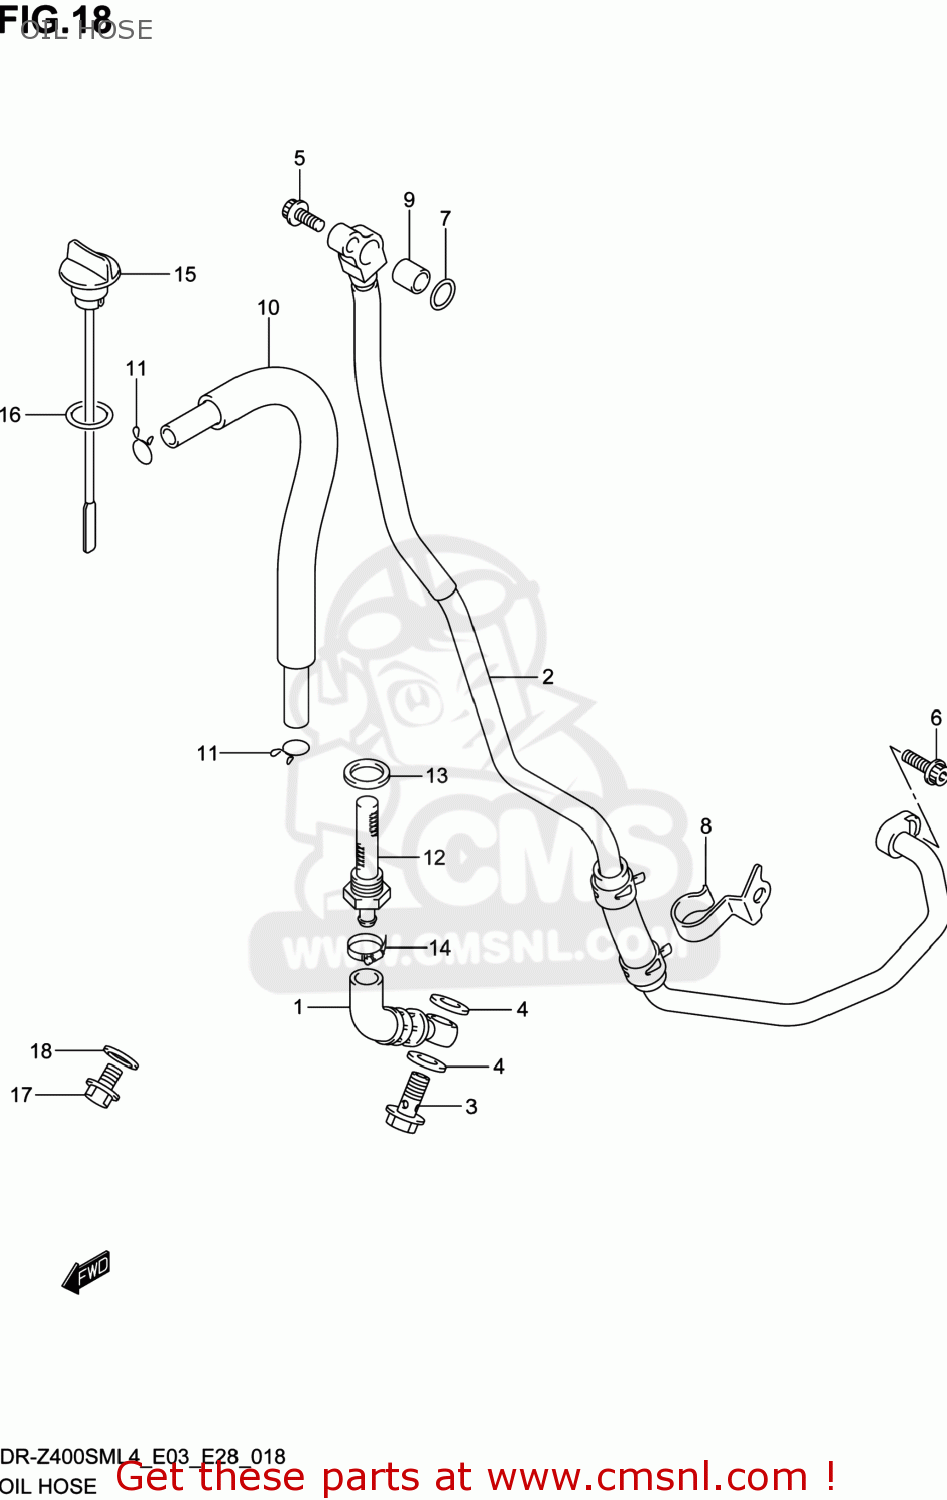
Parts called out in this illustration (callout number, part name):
1	HOSE,OIL TANK,R
2	HOSE,OIL TANK,L
3	BOLT UNION
4	GASKET(14X20X1.5) (NAS)
5	BOLT
6	BOLT
7	O RING(D:2.4,ID:11)
8	CLAMP,OIL TANK HOSE
9	PIN
10	HOSE,OIL TANK OVER FLOW
11	CLIP
12	STRAINER,FRAME HEAD UNDER
13	GASKET(18X22X2) (NAS)
14	CLAMP
15	GAUGE,OIL LEVEL
16	O RING(D:3.1,ID:16.8)
17	PLUG(10X12)
18	GASKET(10X14X3.6) (NAS)
